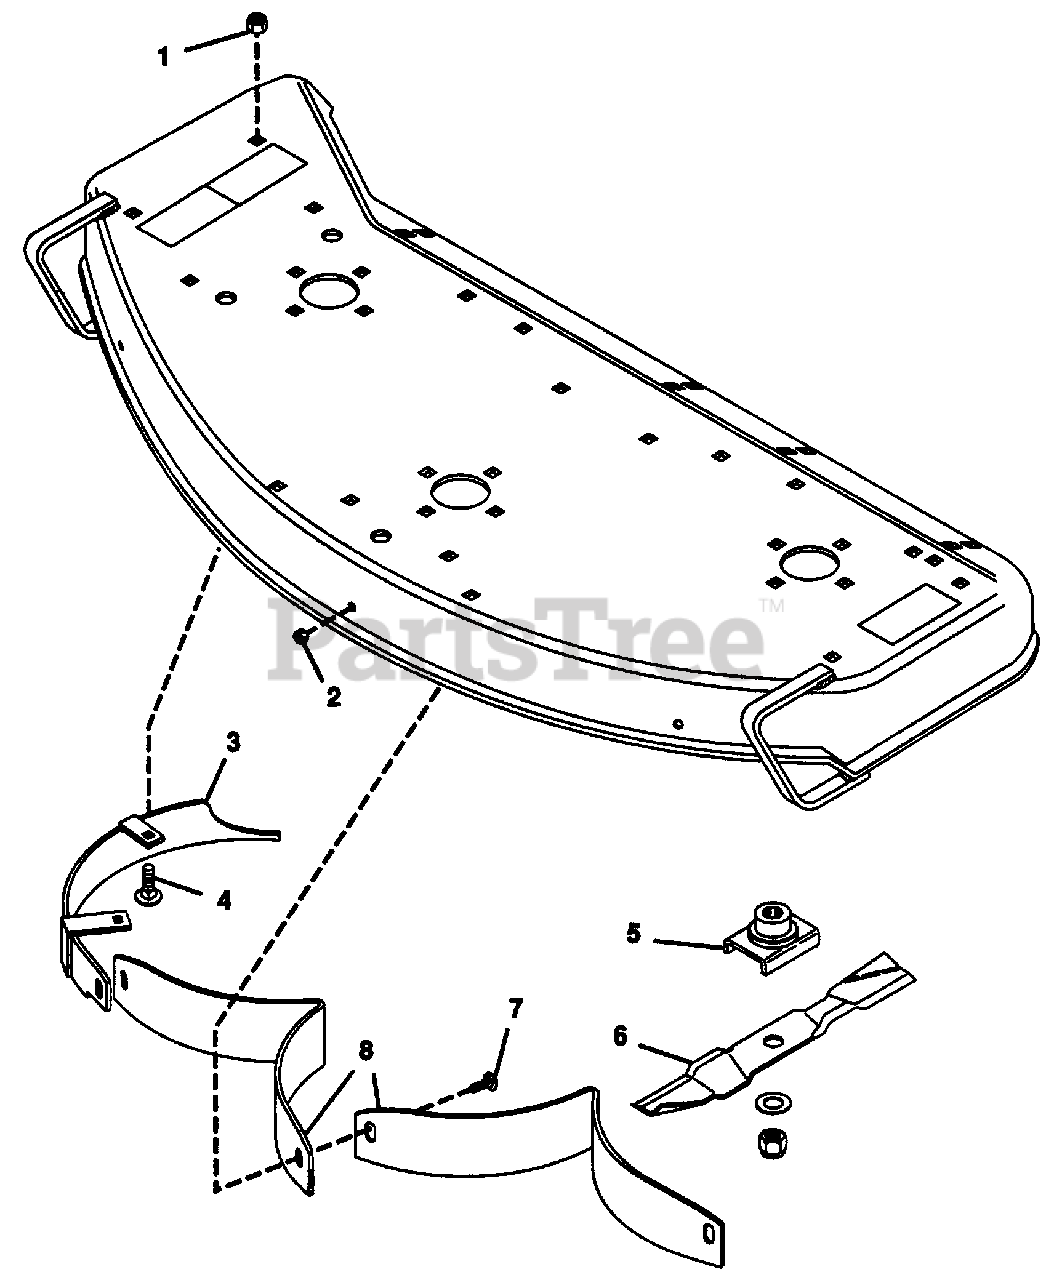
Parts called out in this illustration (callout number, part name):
1	Nut, Lock 3/8-16
2	Nut, Lock 5/16-18
3	Weldment, Chute Baffle
4	Bolt, Carriage 3/8-16x.75
5	Weldment, Blade Cradle
6	Blade, Mulching 50" Mower
7	Bolt, 5/16-18x.625 Rd Hd Sq Nk
8	Baffle, Mulching
